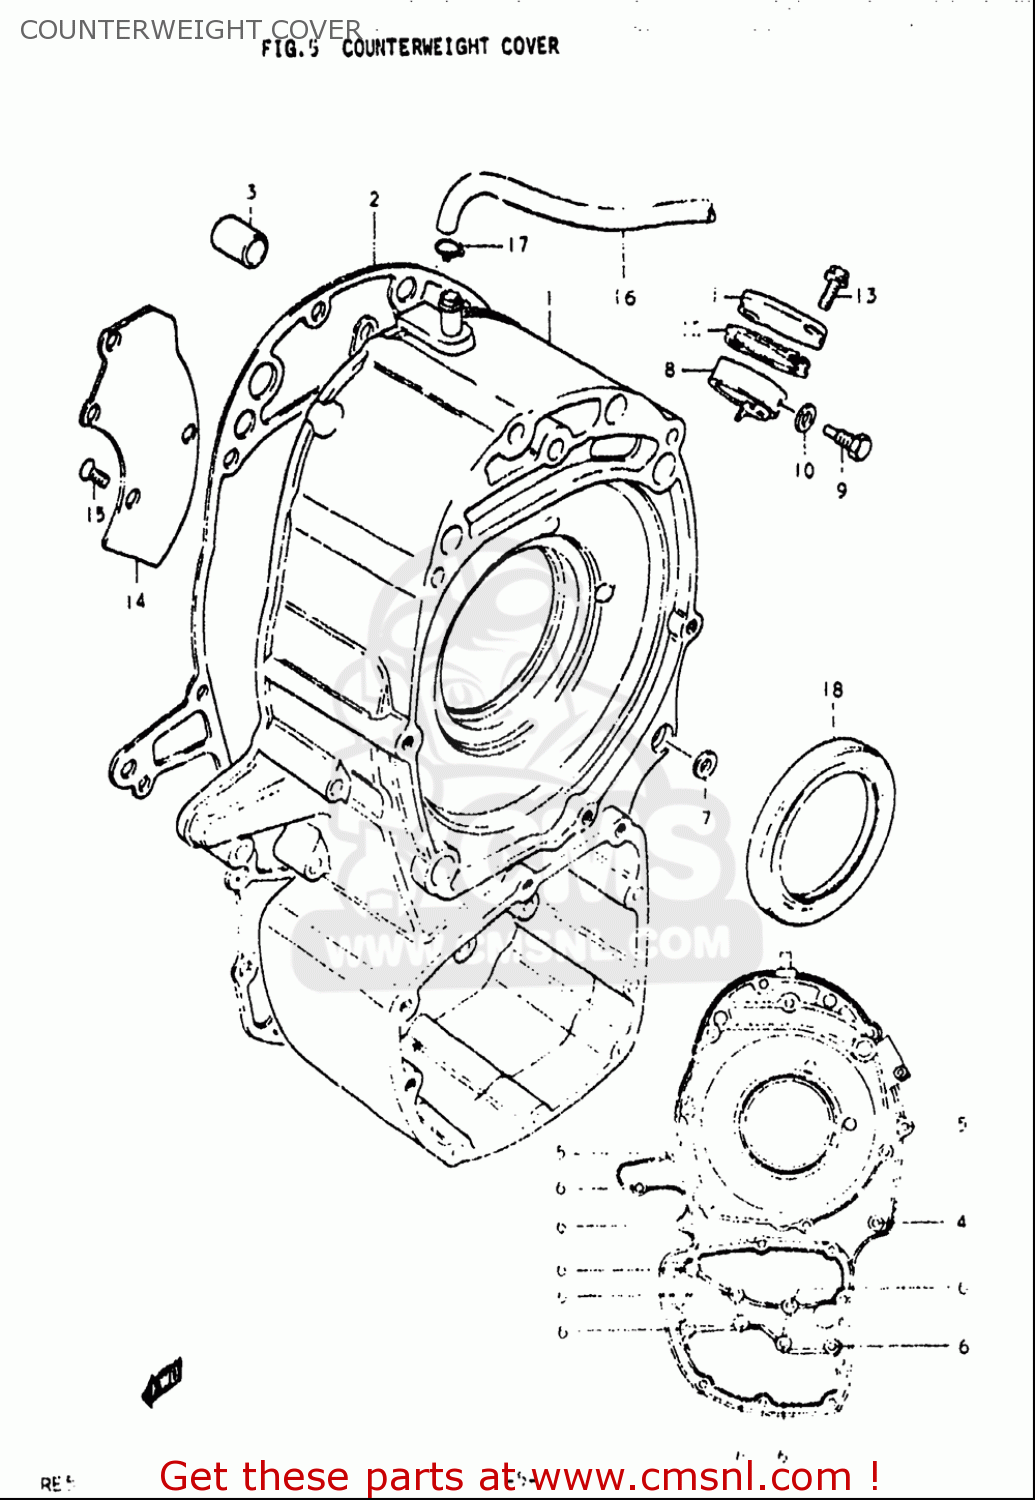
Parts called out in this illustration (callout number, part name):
3	PIN
5	BOLT
6	BOLT
7	WASHER
9	BOLT(6X12)
10	WASHER
13	BOLT
15	SCREW
16	HOSE(7X10.2X2000)
17	CLIP
